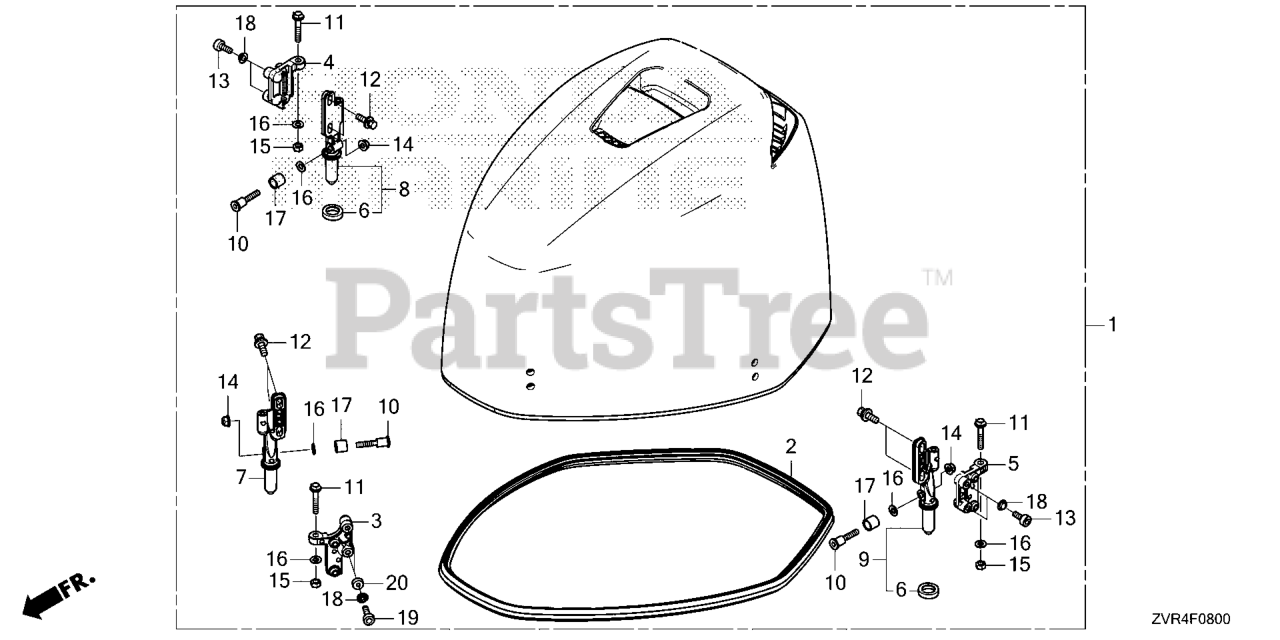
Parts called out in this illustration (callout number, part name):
1	COVER, ENG *NH565*
1	COVER, ENG *NHB14M*
2	SEAL, ENGINE COVER
3	BRACKET, FR. HOOK
4	BRKT, HOOK R (UPPER)
5	BRKT, HOOK L (UPPER)
6	DAMPER, HOOK
7	BRACKET COMP FR.
8	BRACKET COMP R, HOOK
9	BRACKET COMP L, HOOK
10	BOLT, SOCKET (6X25)
11	BOLT, FLANGE (6X35)
12	BOLT-WASHER (6X22)
13	BOLT, SOCKET (6X16)
14	NUT, SELF-LOCK (6MM)
15	NUT, HEX. (6MM)
16	WASHER, PLAIN (6MM) Use up to Frame SN 4800342.
17	ROLLER, HOOK
18	COLLAR, DISTANCE (6.5X9X3)
19	BOLT, SOCKET (6X20)
20	WASHER, PLAIN (6MM)
